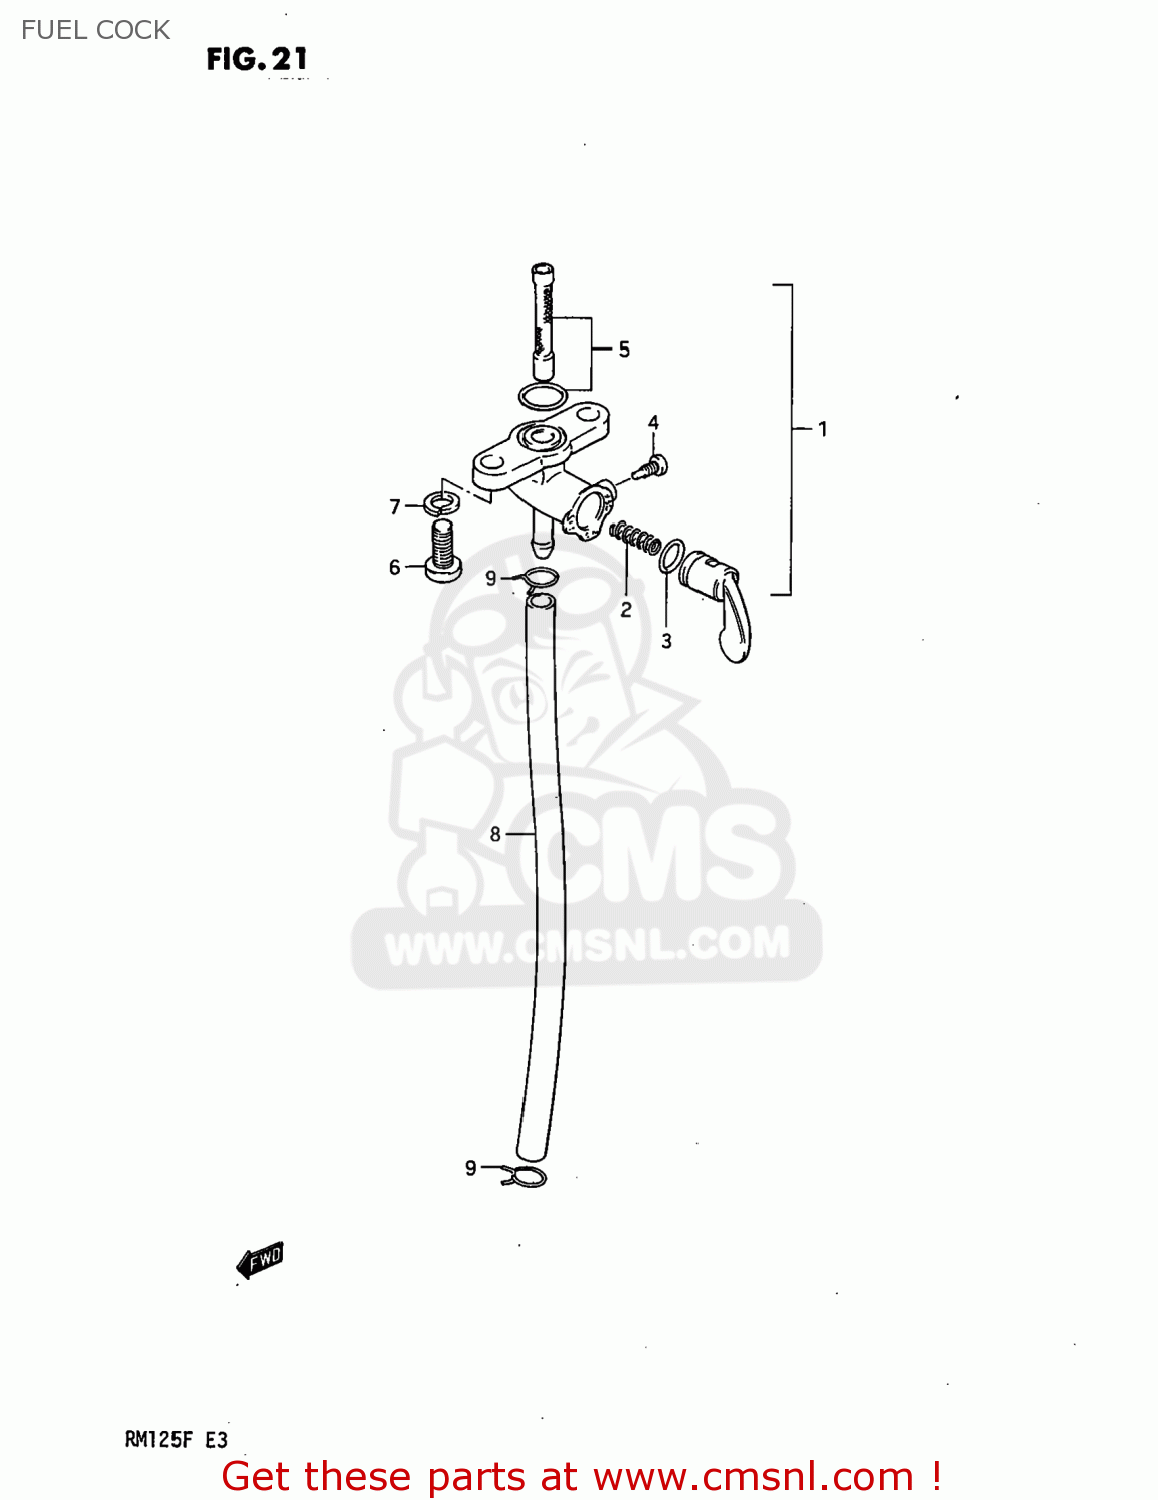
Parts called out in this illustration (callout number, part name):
1	COCK ASSY,FUEL
2	SPRING,FUEL COCK VALUE
3	O RING,LEVER
4	SCREW
5	FILTER SET FUEL
6	SCREW
7	LOCK WASHER
8	HOSE,FUEL
9	CLAMP
